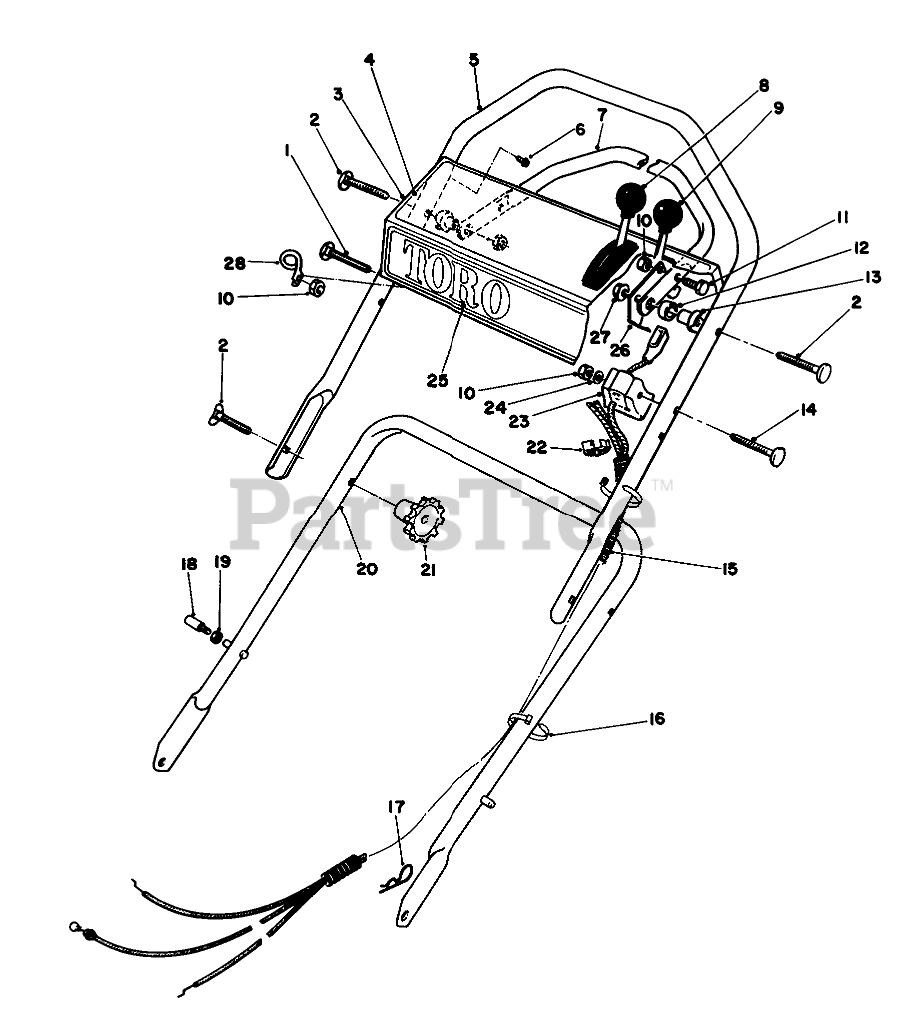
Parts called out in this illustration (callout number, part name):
1	HANDLE SCREW
2	5/16-18 X 2 HNDLE SCREW
3	Panel-Control (Incl. Ref. #4)
4	Decal-Instructions
5	Handle-Upper
6	Screw
7	Bar-Control
8	SERVICE TRACT. CONTROL
9	Control-Throttle/Choke Bend Type 2 Sheath Lg.41" (104.1 cm) Wire Lg.21/4" (5.7 cm)
10	NUT-LOCK, NI
11	SCREW-HH
12	SPACER-NYLON
13	SPACER-SUPPORT
14	HANDLE SCREW
15	CONT. CABLE COVER
16	TIE-CABLE
17	PIN-COTTER, HAIR
18	CHOKE DECAL
19	NUT-LOCK, NI
20	LOWER HANDLE ASM
22	FITTING-RING
23	SUPPORT-CABLE
24	WASHER-FLAT
25	Decal-Toro
26	Lever-Control
27	NUT-LOCK, NI
28	Guide
